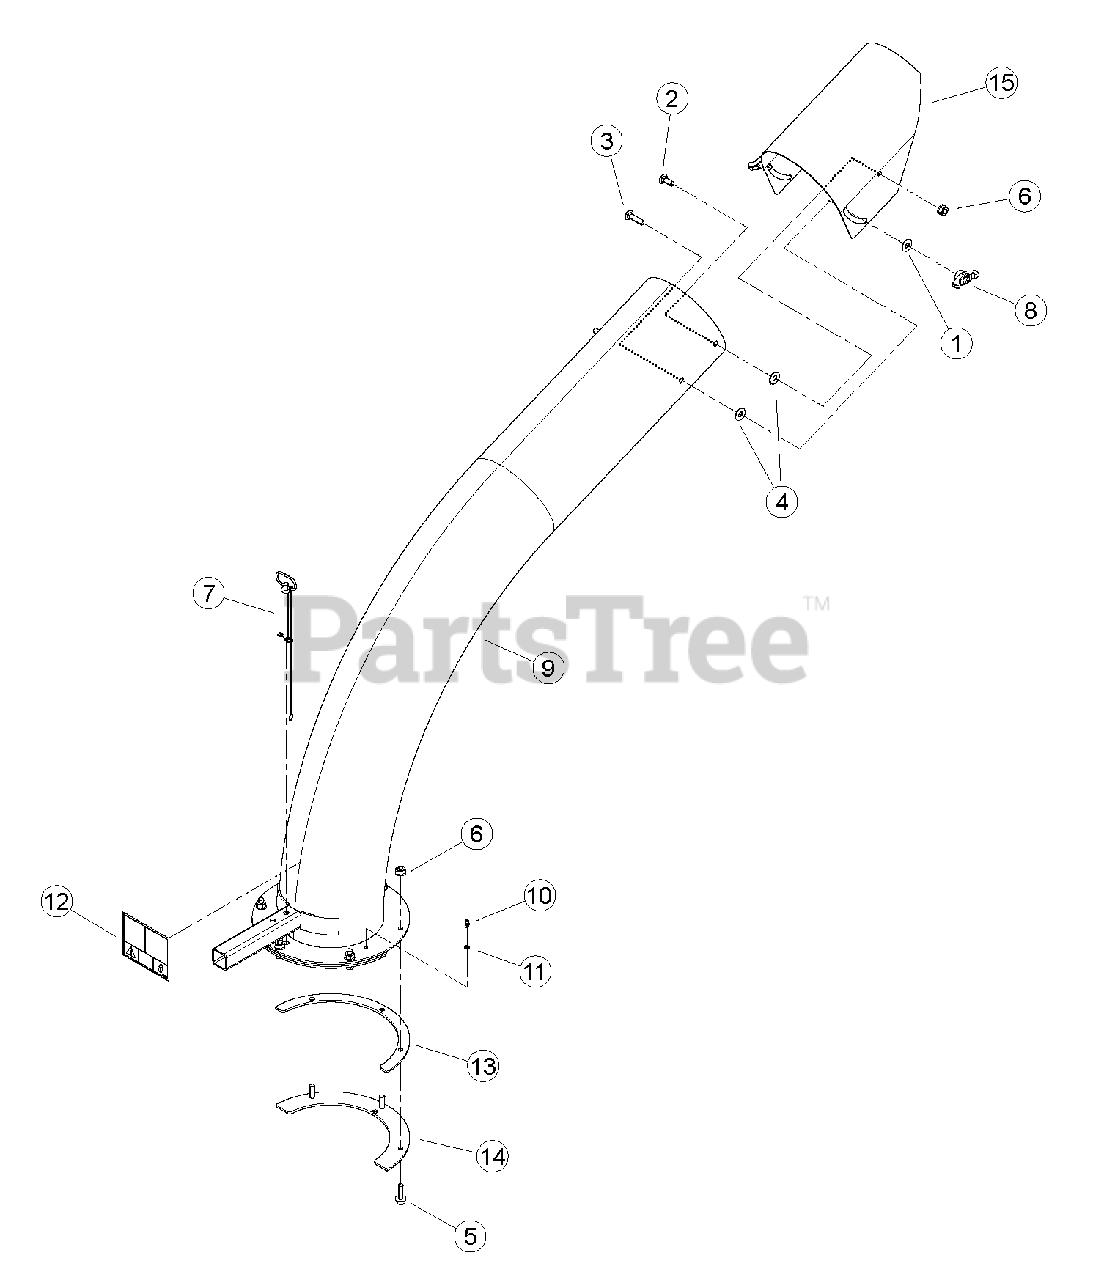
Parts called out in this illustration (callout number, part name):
1	WASHER, 3/8" FLAT ZP
2	BOLT, 3/8 X 1" GR5 CRG NC ZP
3	BOLT, 3/8 X 1-1/2" GR5 CRG NC ZP
4	WASHER, 1/2 SAE FLAT
5	BOLT, 3/8 X 1-1/4 FLANGE NC
6	NUT, 3/8-16 NYLOCK FLANGE
7	PIN, 3/8 X 4.25" DISCHARGE
8	KNOB, 3/8-16 UNC FEMALE TEE
9	ASSEMBLY, 8 INCH DISCHARGE CHUTE
10	FITTING, 1/4 SELF-TAP GREASE
11	WASHER, FLAT .254 X .400 X .048
12	DECAL, DISCHARGE DEBRIS & LOCK
13	RING, DISCHARGE SPACER
14	RING, DISCHARGE CLAMP
15	CAP, 8 INCH DISCHARGE CHUTE
